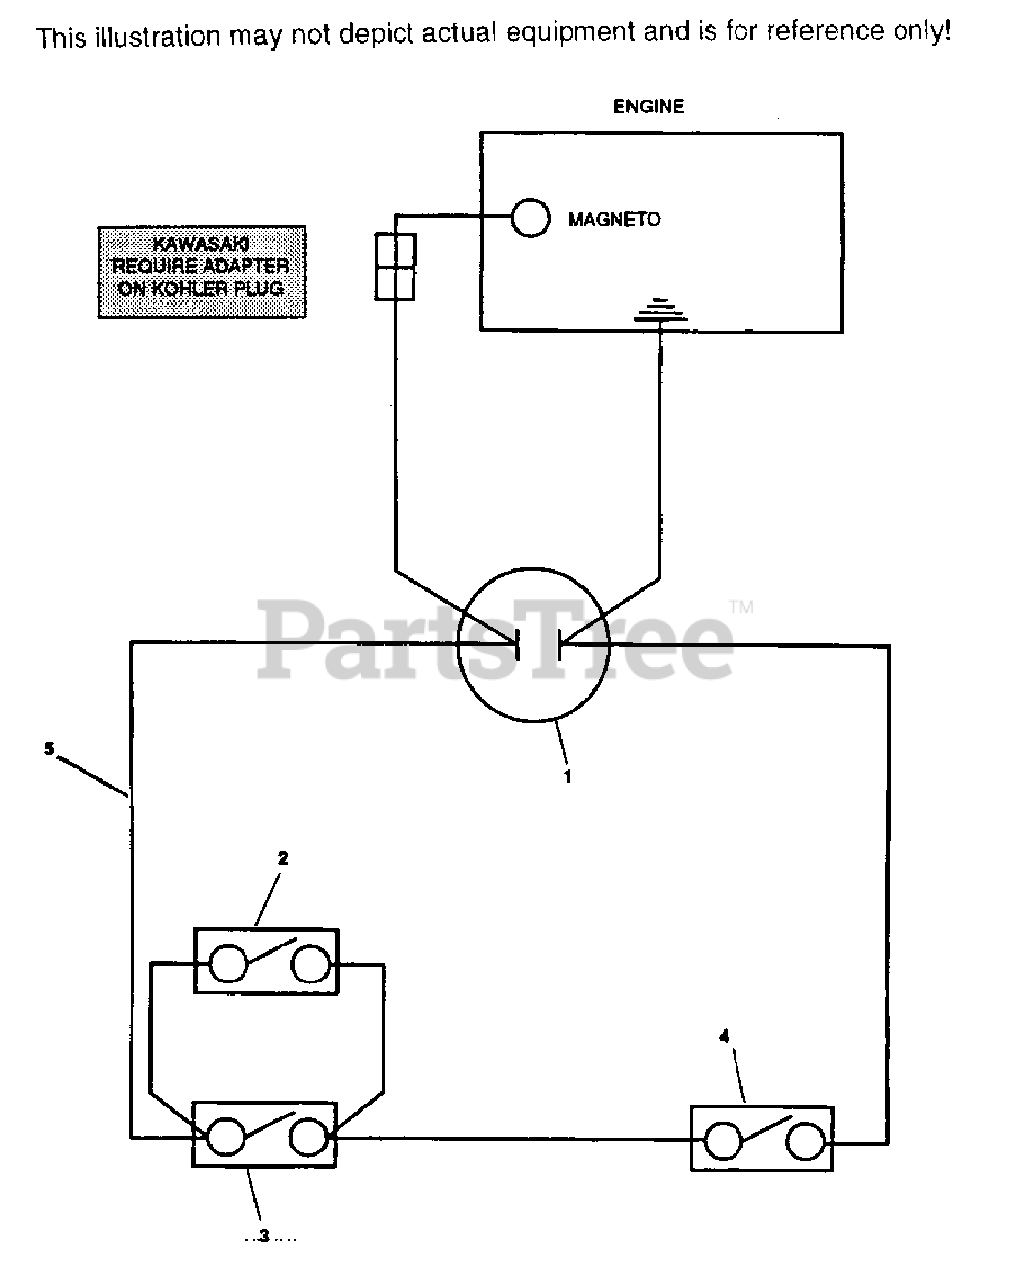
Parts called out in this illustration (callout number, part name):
1	SWITCH, IGNITION
2	SWITCH, NEUTRAL SAFETY N.C.
3	SWITCH, CLUTCH SAFETY N.C.
4	SWITCH, PRESENCE CONTROL SAFETY N.C.
5	WIRE HARNESS
